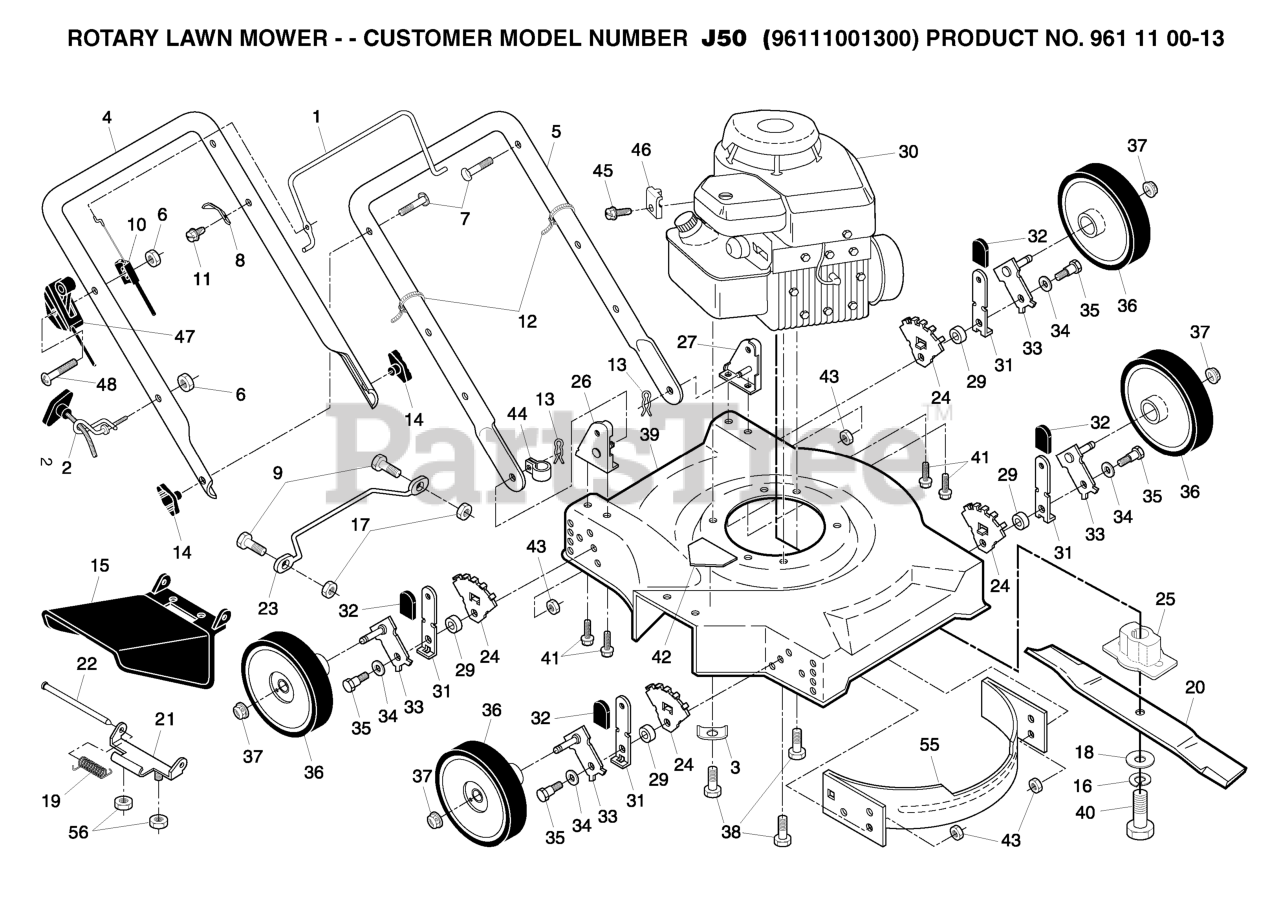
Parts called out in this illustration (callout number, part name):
1	BAIL.CONT.D.STRAIGHT.PUSH.BLK
2	RB GUIDE.ROPE.STD.BLK.ZIN WSL
3	WASHER.ENGINE.BZP
4	HANDLE.UPPER.FGD/PUSH.BLACK
5	LOWER HANDLE
6	NUT
7	BOLT, HANDLE 5/16-18X1.75
8	BRACKET UPSTOP
9	REPL BY 817 02 10-08
10	CABLE.CONTROL.MZR.RH.SP/PUSH
12	TIE GUIDE
13	HAIRPIN COTTER
14	KNOB, DEFLECTOR
16	LOCKWASHER
18	WASHER,HARDEN
19	SPRING TENSION
20	BLADE.20.MULCH.(50DK,6020MD)
21	HINGE DEFLECTOR
24	WHEEL ADJUST BRACKET
25	BLADE ADAPTOR
26	HANDLE BRACKET ASM. RH
27	HANDLE BRACKET ASM. LH
29	RP SPACER HT ADJ
31	SELECTOR SPRING
33	AXLE, REAR
34	WASHER.BELLEVILLE (3 2 LB)
35	BOLT
37	HEX FLANGE LOCKNT
38	BOLT 3/8-16X1-1/8
40	SCREW, HEX HD 3/8-24 X 1-3/8
41	SCREW.5/16-18X3/4
42	DECAL.INTERNATIONL.CUTFINGER
43	LOCKNUT PM
44	CLIP.CABLE.BLK
45	SCREW.HEX.HEAD.WASHER.10-16
46	CABLE CLAMP(ENGINE)
47	THROTTLE CONTROL
55	FRONT BAFFLE
56	LOCKNUT.NYLOC.1/4-20
